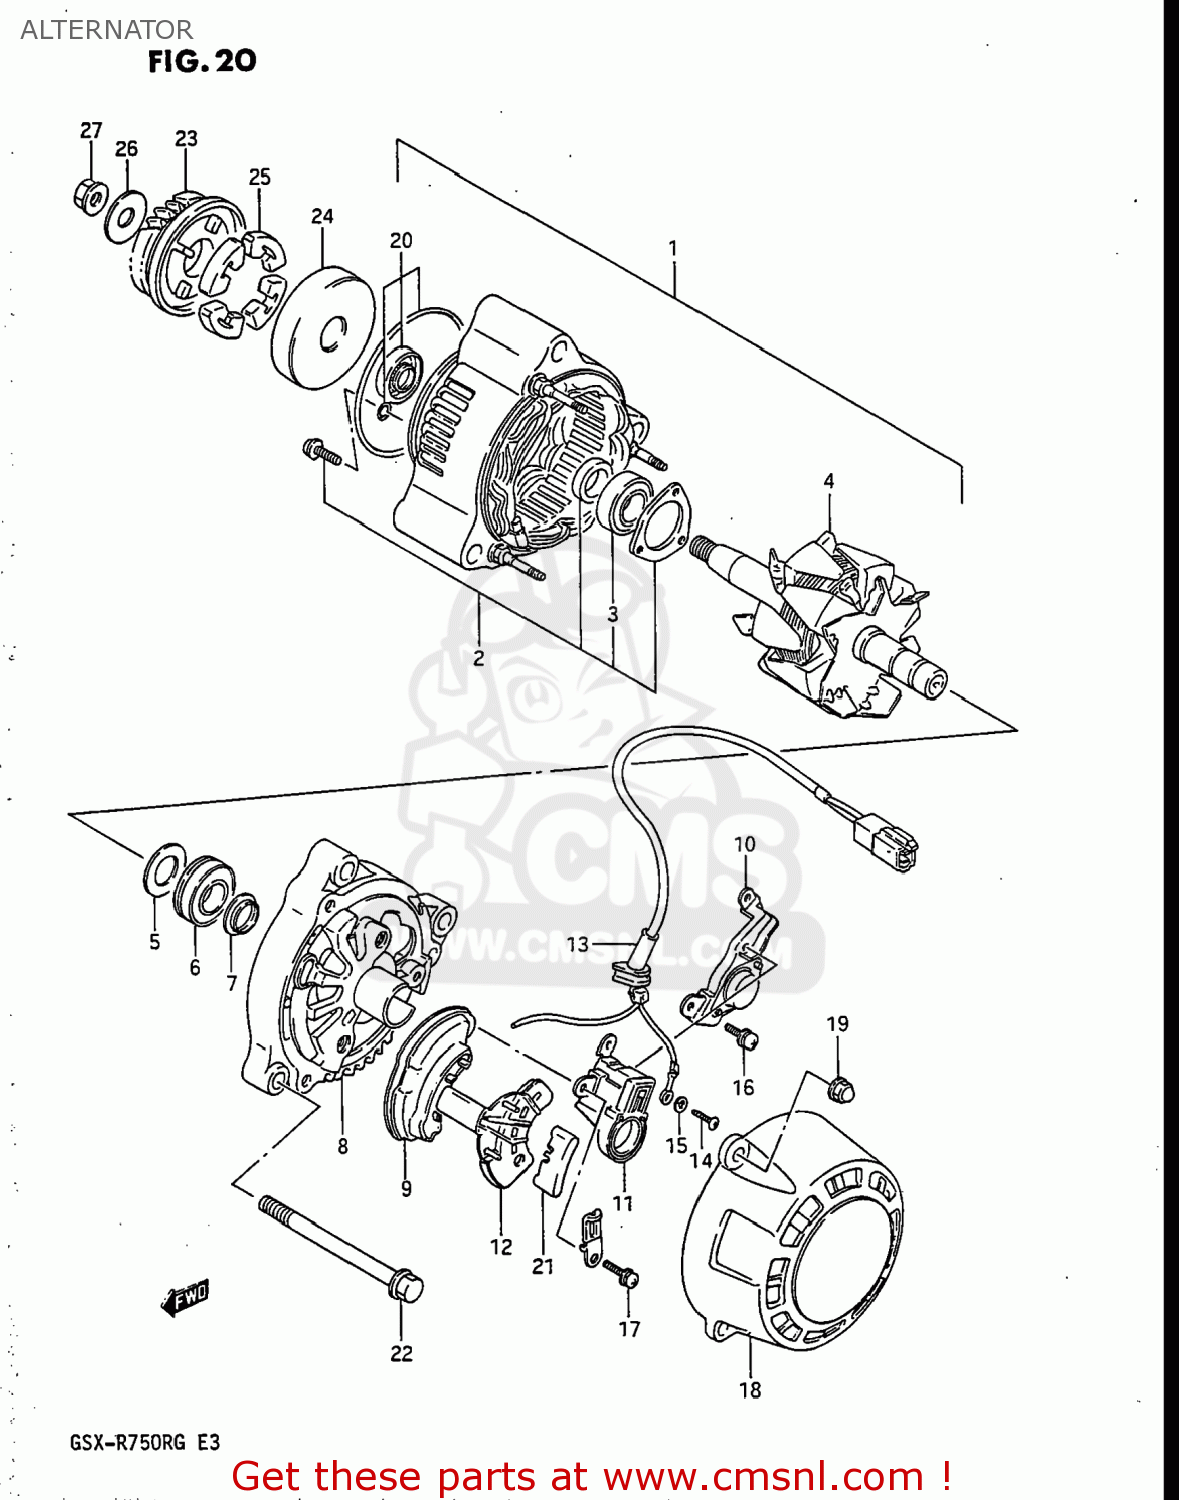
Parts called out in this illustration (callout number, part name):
1	ALTERNATOR ASSEMBLY
2	FRAME,DRIVE END
3	BEARING
4	ROTOR
5	COVER (2)
6	BALL BEARING,ALTERNATOR
7	COVER(2)
8	FRAME,END
9	HOLDER,RECTIFIER
10	REGULATOR
11	HOLDER,BRUSH
12	COVER,RECTIFIER
13	WIRE,LEAD
14	SCREW
15	LOCK WASHER
16	SCREW
17	SCREW
18	COVER
19	NUT
20	OIL SEAL SET
21	BUSH
22	BOLT (8X90)
23	GEAR,GENERATOR DRIVEN
24	HOUSING,GENERATOR GEAR
25	DAMPER,GENERATOR DRIVEN
26	WASHER
27	NUT
